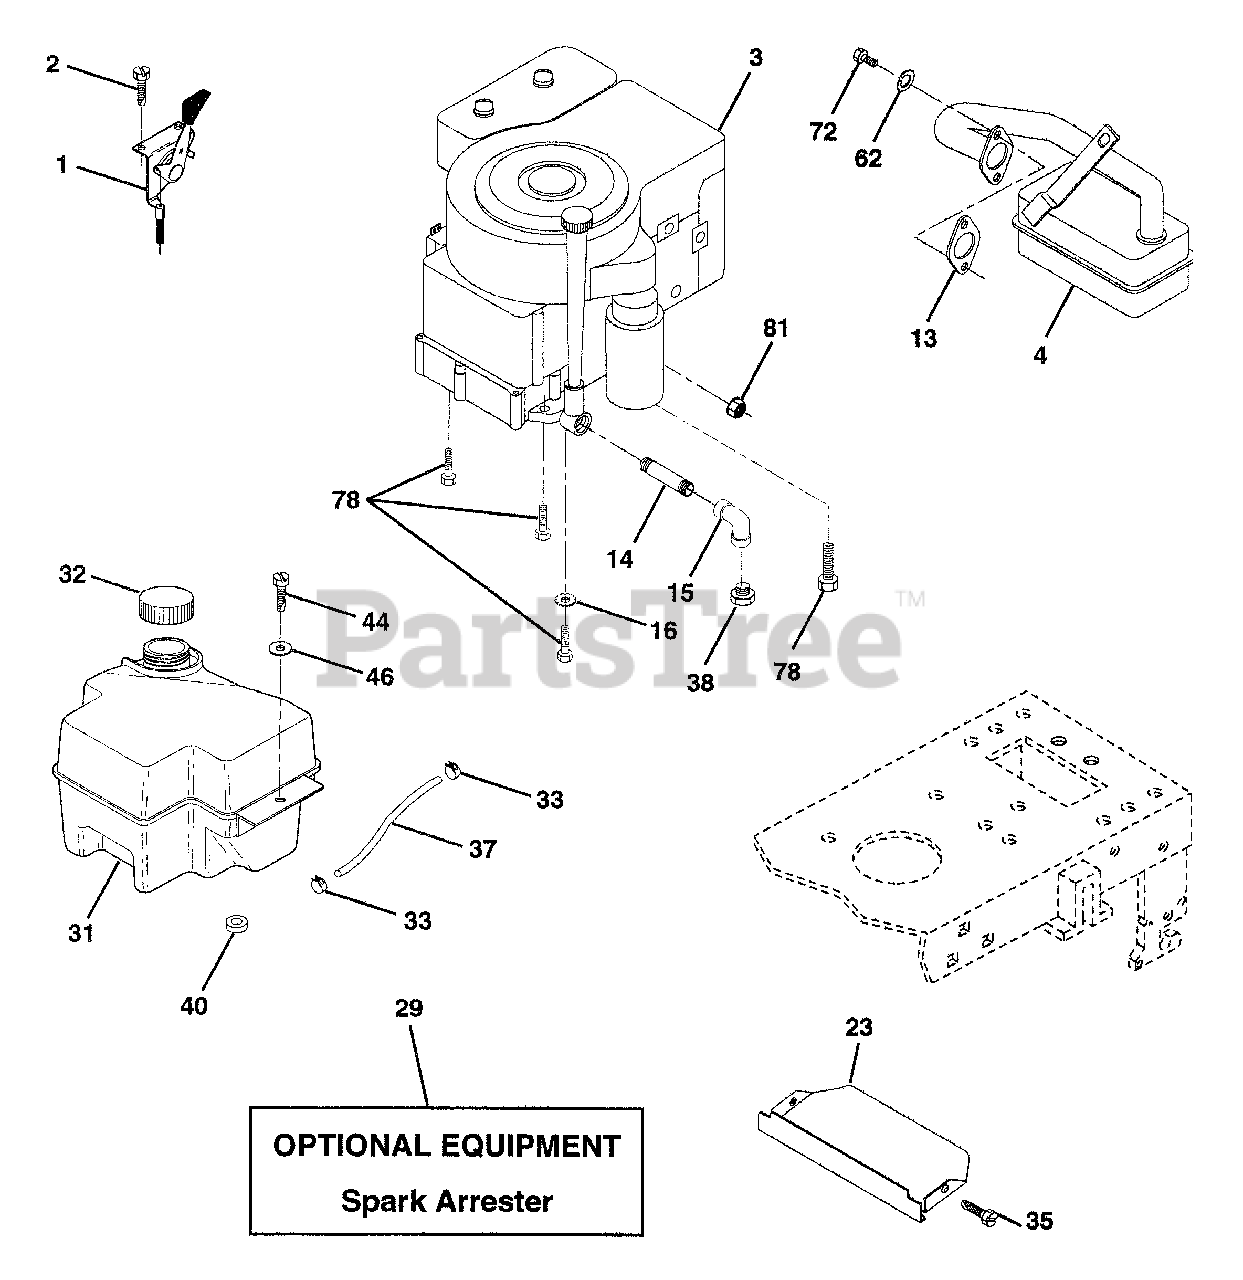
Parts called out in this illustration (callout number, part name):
1	Control Th/ch 23 5 LH Flag
2	Screw Hex Thd Cut 1/4-20x5/8 T
4	Muffler LT B&S 12/12.5/13HP
13	Gasket Eng 1 313 Id Tin Plated
14	Nipple Pipe 3/8 Npt X 3"
15	Elbow Std 90 Degree 3/8-18 Npt
16	Washer Lock Ext Tooth 3/8
23	Shield Brn/Dbr Guard
29	Kit Spark Arrestor (Flat Scrn)
31	Tank Fuel Front 2 00
32	Cap Asm Fuel W/sym Vented
33	Clamp Hose Black
35	Screw
37	Line Fuel 20"
38	Plug Oil Drain
40	Bushing Snap Nyl Blk Fuel Line
44	Screw Hexwsh Thdrol 1/4-20x3/4
46	Washer 9/32 X 7/8 X 16 Ga
62	Washer Lock Hvy Hlcl Spr 5/16
72	Screw Hexhd Cap 5/16-18x 3/4
78	Screw Thdrol 3/8-16x1-1/4 TYTT
81	Nut Flange 1/4-20 Starter Nut
